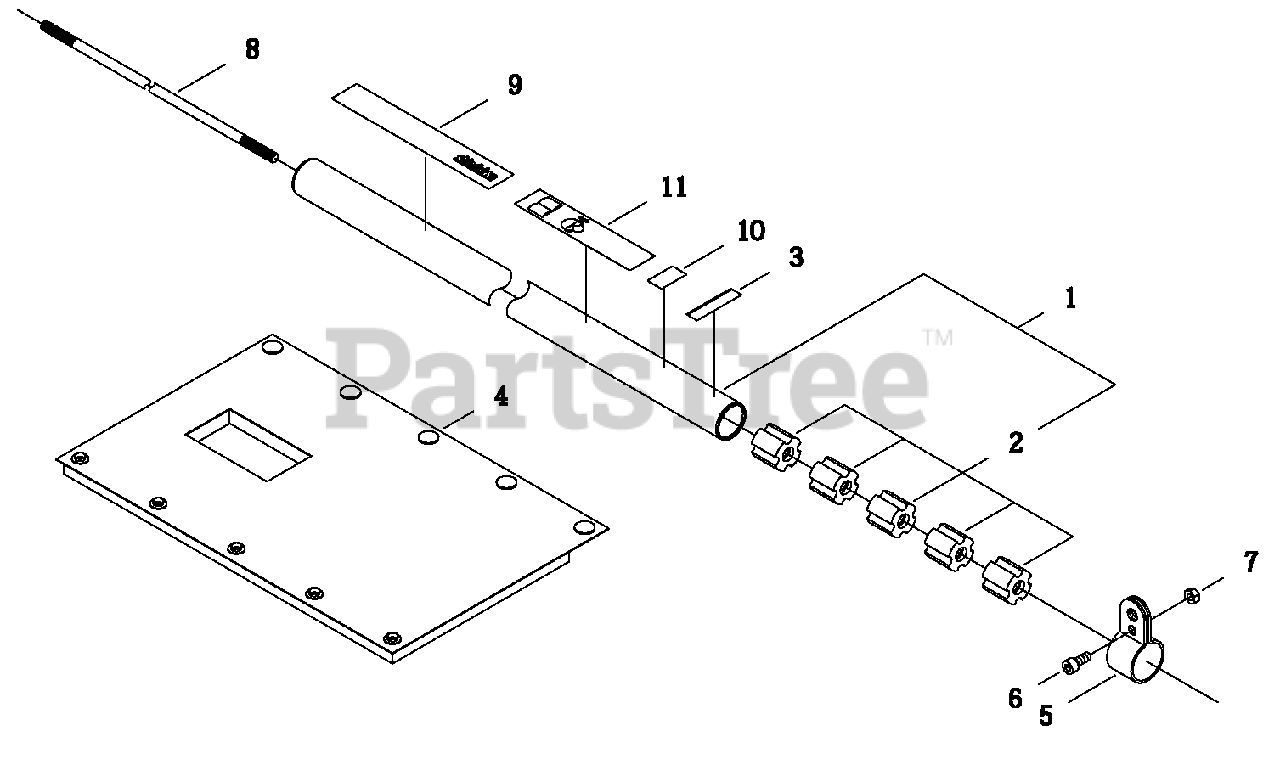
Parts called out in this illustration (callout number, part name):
1	MAIN PIPE ASSY
2	BUSHING
3	LABEL - ALIGNMENT
4	CUSHION, MAIN PIPE
5	HANGER
6	BOLT 5×12
7	NUT M5
8	MAINSHAFT
9	LABEL, SHINDAIWA PROFESSIONAL
10	LABEL, HANDLE
11	LABEL, CAUTION (BLADE CAPABLE)
